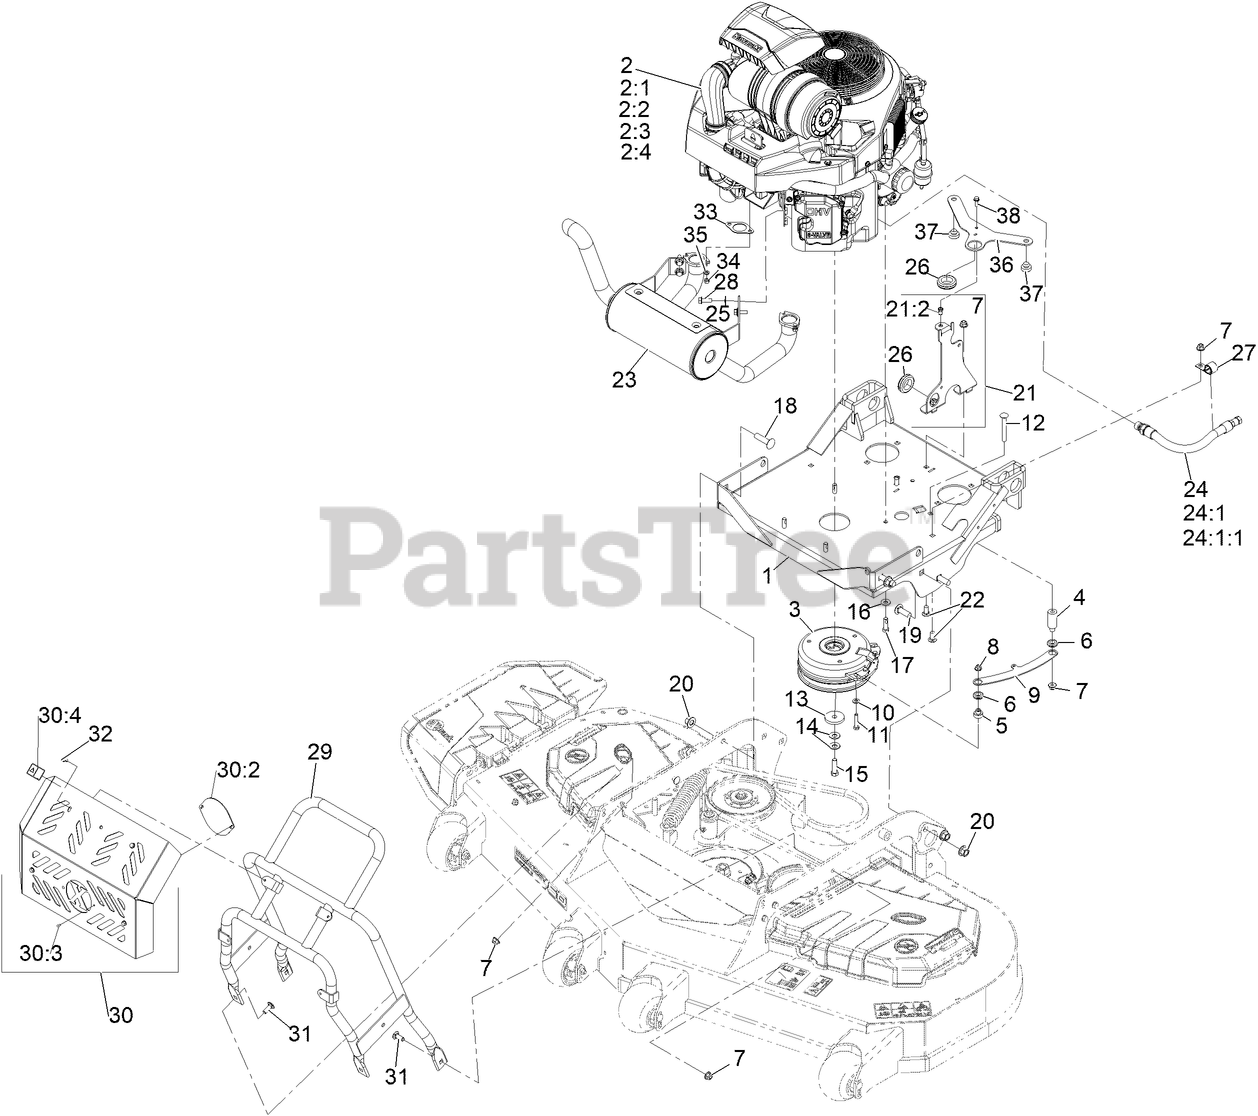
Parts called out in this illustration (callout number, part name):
1	ASM-ENGINE DECK
2:1	Kawasaki 49065-7007 Engine Oil Filter
2:2	Kawasaki 49019-0031 Fuel Filter
2:3	Kawasaki 11013-7045 Safety Filter
2:4	Kawasaki 11013-7044 Engine Air Filter
5	SPACER-STEPPED
6	GROMMET-RUBBER
7	NUT-HF, NI
8	NUT-HF, NI
9	LINK-CLUTCH ANCHOR
10	WASHER-PLAIN
11	SCREW-HH
12	SCREW-CARR
13	WASHER-CLUTCH
14	WASHER-SPRING
15	SCREW-HH 7/16-20 X 1 1/2 W/LOCTITE
16	WASHER-BELLEVILLE
17	Screw-HH, Patch
18	SCREW-CARR
19	Screw-CARR, Sn
20	Nut-Lock 1/2-13
21	ASM-HOSE GUIDE
21:2	Nut-Clinch, Hex
22	SCREW-CARR
23	MUFFLER- 5.00 OD, 1.5-IN TP
24	ENGINE OIL DRAIN HOSE ASM
24:1	PLUG-HH
24:1:1	O-RING
25	WASHER-BELLEVILLE
26	GROMMET
27	CLIP-OPEN J, COATED
28	SCREW-HHF
29	FRAME-ENGINE GUARD
30	COVER ASM-ENGINE GUARD
30:2	PLATE-LOGO
30:3	RIVET-POP
30:4	DECAL-WARNING
31	SCREW-CARR
32	SCREW-HWH
33	GASKET, EXHAUST
35	WASHER-LOCK
36	PLATE-HOLD DOWN
37	BUMPER-RUBBER
38	SCREW-HHF
